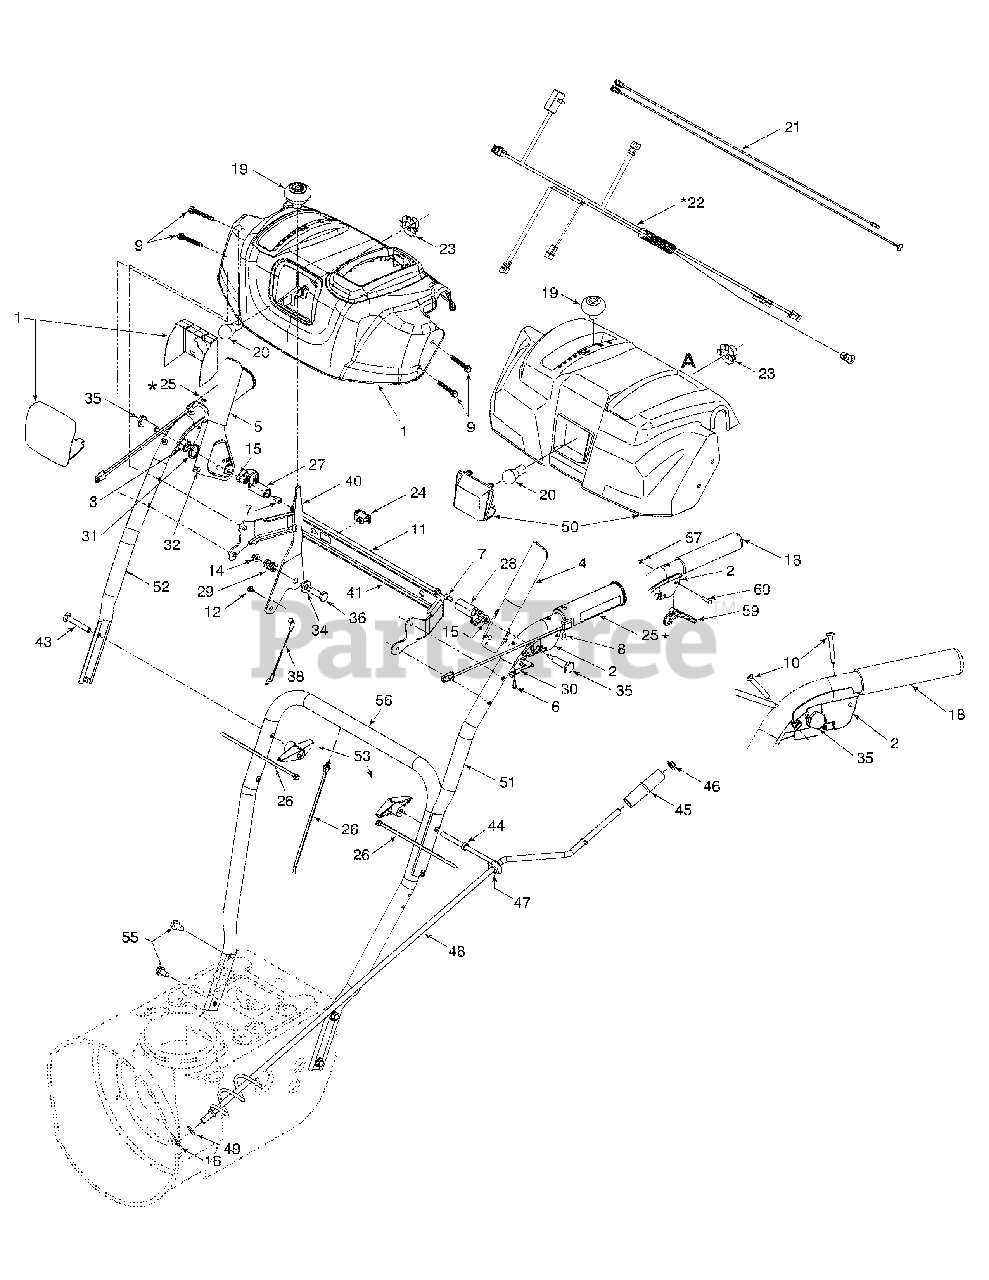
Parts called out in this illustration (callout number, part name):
1	Handle Panel Assembly - Yellow
1	Handle Panel Assembly - Black
1	Handle Panel Assy - Black w/ Chute Control
2	LH - Clutch Lock Handle Assembly
3	RH - Clutch Lock Handle Assembly
4	Engagement Handle Assembly - LH
5	Engagement Handle Assembly - RH
6	Screw #8-16 x .50
7	Screw 1/4-20 x .375
8	Oval HD C-Sunk Scr #10 x 5/8
9	Hex TT-Tap Scr. 1/4-20 x 1.625
10	Oval C-Sunk HD Scr. 10-24 x 1.375
11	Pivot Rod
14	Hex L-Flanged Nut 1/4-20 Gr. F Nylon
15	Hex Shoulder Nut 1/4-20
16	Int. Cotter Pin .072 x 1.13'' Lg
19	Shift Knob
19	Shift Knob - Yellow
20	Lamp #1295
20	Lamp
21	Wire Harness
22	Heated Grip Wire Harness
23	Socket
24	Switch
25	Heated Grip Wire Harness
26	Cable Tie 19 x 8.39''
26	Cable Tie
27	Locl Plate
28	Clutch Lock Cam
29	Compression Spring .38 ID x .88 Lg
30	Spring : Clutch Lock
31	Torsion Spring .8156 x .3038
32	Rubber Bumper
34	Flat Washer .38 ID x .87 OD x .09
35	Shoulder Screw 1/4-20 x 1.345
36	Shoulder Screw .374 Dia x 1.05 Lg
38	Selector Speed Cable
43	Carriage Bolt 5/16-18 x 2.25
44	Chute Crank Eye Bolt Special
45	Knob 1.0 x 3.2
46	Push Nut 3/8'' Rod
47	Fgrommet
49	Flat Washer .406'' ID x .75'' OD
53	Handle Knob Assembly
55	Hex TT Screw 3/8-16 x 0.75
57	E-Ring
59	Steering Control
60	Pin 3/16
